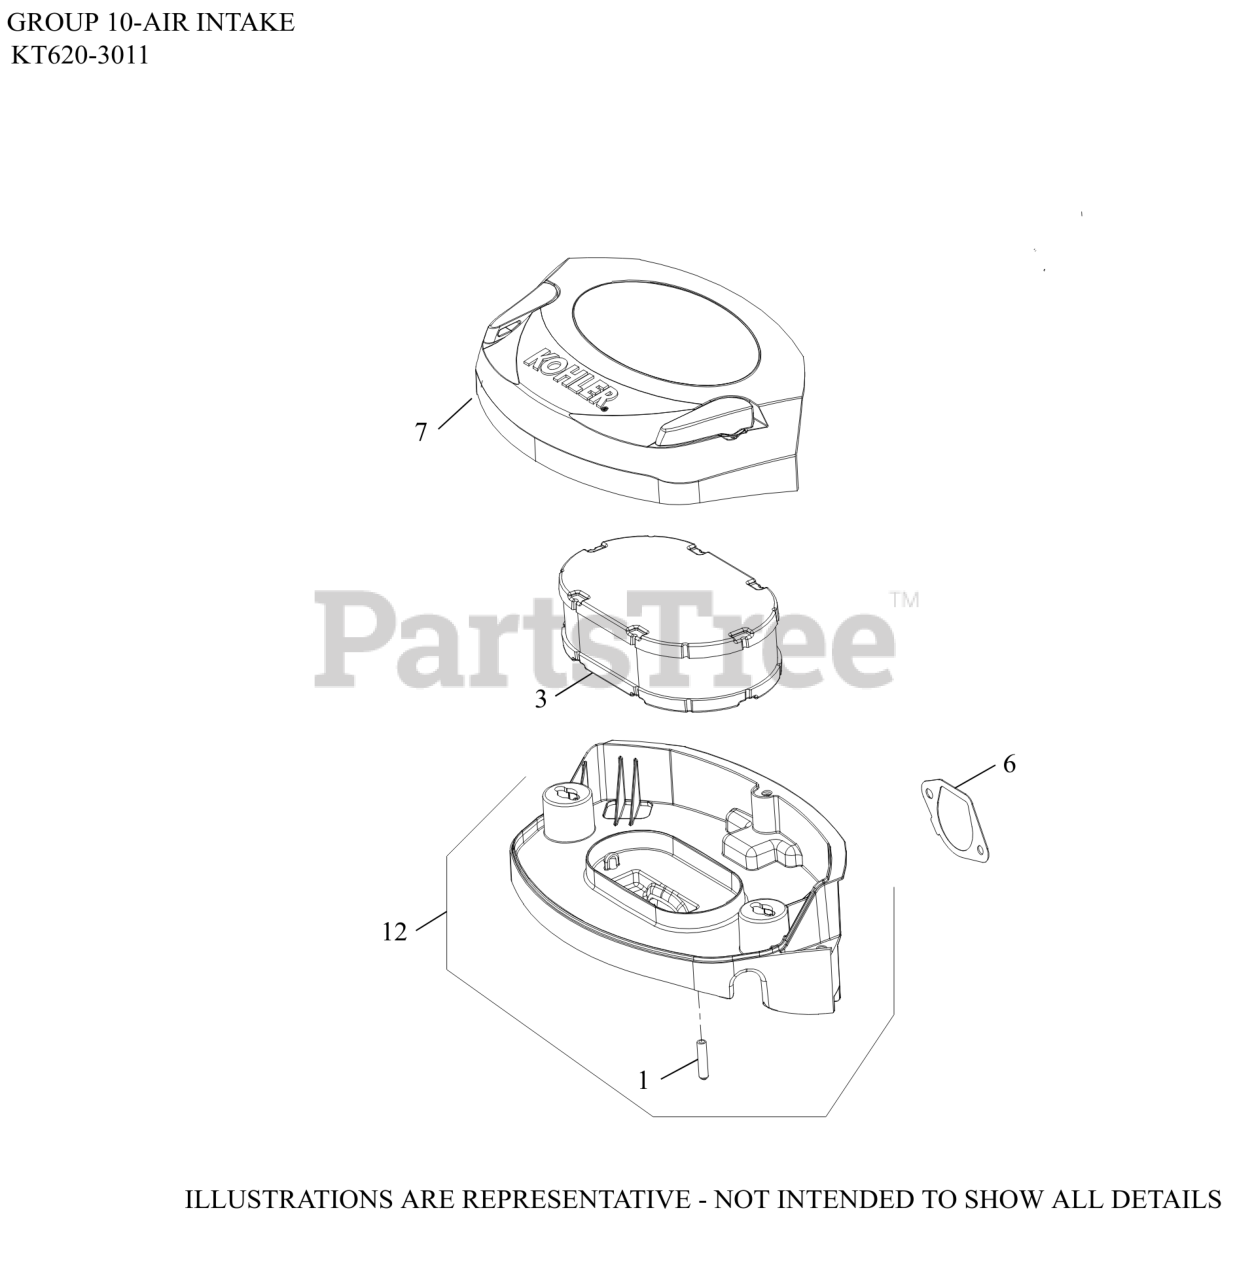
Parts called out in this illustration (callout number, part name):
1	CAP, MASKING
3	ELEMENT, AIR FILTER
6	GASKET, AIR CLEANER BASE
7	COVER ASSEMBLY, AIR CLEANER
12	BASE ASSY, AIR CLEANER
